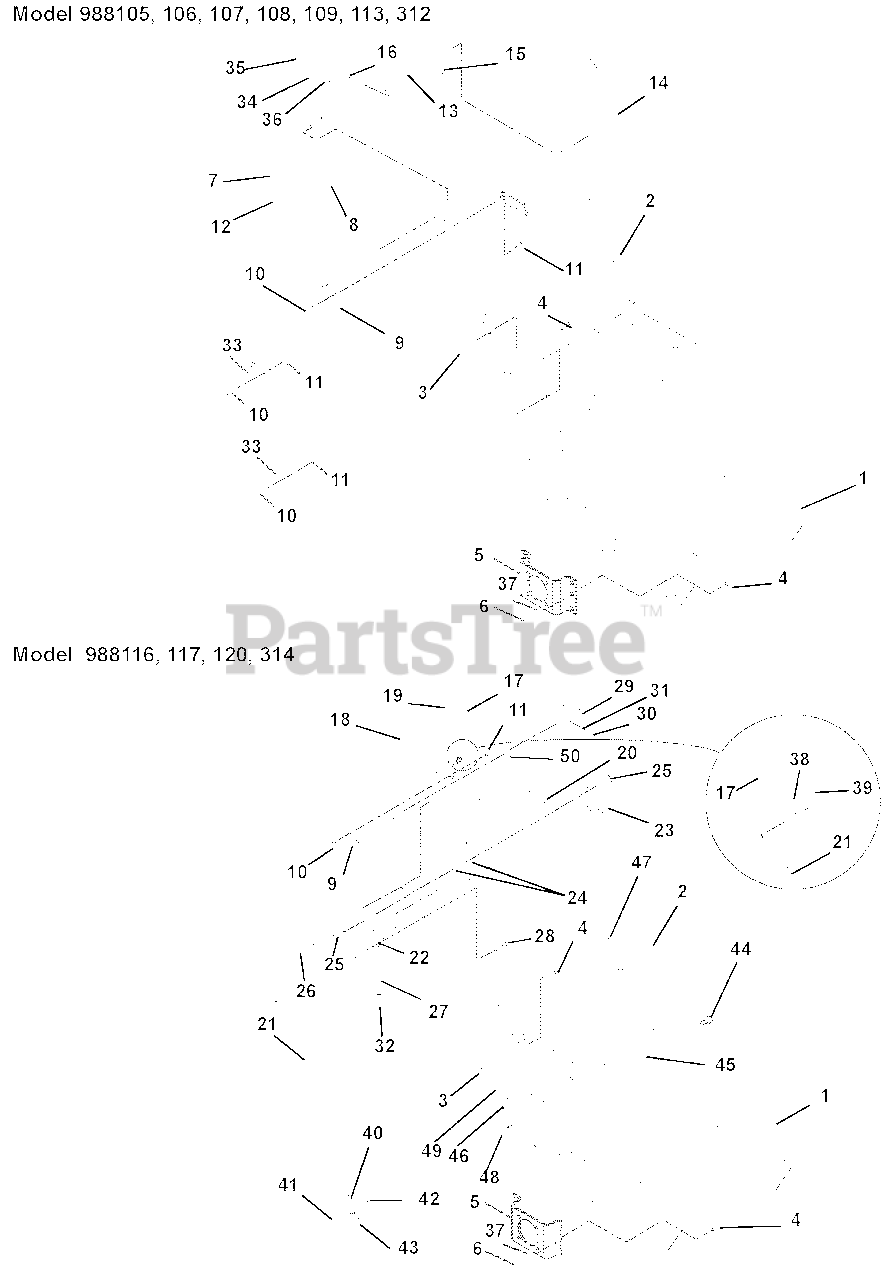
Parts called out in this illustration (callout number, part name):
1	Kit-Frame with Decals
2	Kit-Handlebar with Decals HR15 (105 - 107, 113, 312)
3	Bolt-Hex .38-16 x 1.00 Grade 5
4	Nut-Locking-Nylon .38-16
5	Bracket, Wheel Motor Left Hand (105, 107, 108, 116, 120, 312, 314)
6	Bolt-Hex .38-16 x 1.00 Grade 5
7	Grip, Handlebar (105, 106, 107, 108, 109, 113, 312)
8	Caplug, Handlebar (105, 106, 107, 108, 109, 113, 312)
9	Switch, Double Pole(105, 106, 107, 108, 109, 113, 312)
10	Screw, Machine 10-24 x .75 Hex Washer Head (105, 106, 107, 108, 109, 113, 312)
11	Nut-Locking-Nylon 10-24 with Insert (105 - 109, 113, 312)
12	Lever, Right Hand-Operator Presence (105, 106, 107, 108, 109, 113, 312)
13	Weldment, Pivot Tube (105, 106, 107, 108, 109, 113, 312)
14	Lever, Left Hand-Operator Presence (105, 106, 107, 108, 109, 113, 312)
15	Screw-Tapping 8-32 x .50 Hex Washer Head (105, 106, 107, 108, 109, 113, 312)
16	Spring-Tension .047 x .438 x 1.45 (105, 106, 107, 108, 109, 113, 312)
17	Weldment, Lever-Right Hand Speed Control(116, 117, 120, 314)
18	Lever- Operator Presence(116, 117, 120, 314)
19	Grip- Handlebar(116, 117, 120, 314)
20	Weldment- Speed Control Stop(116, 117, 120, 314) (Serial # 101-2999)
21	Rod, Steering (116, 117, 120, 314)
22	Weldment, Control Stop Limiter-Right Hand(116, 117, 120, 314) (Serial # 101-2999)
23	Weldment, Control Stop Limiter-Left Hand(116, 117, 120, 314)
24	Nut-Locking-Top-Flange .31-18(116, 117, 120, 314)
25	Bolt-Hex .31-18 x 1.75 Grade 5(116, 117, 120, 314)
26	Weldment, Speed Control Pivot- Right Hand(116, 117, 120, 314)
27	Lever- Control Stop Lock(116, 117, 120, 314) (Serial # 101-2999)
28	Bolt-Round Head Square Neck .31-18 x .75 Grade 5 (116, 117, 120, 314) (Serial # 101-2999)
29	Actuator, Switch(116, 117, 120, 314)
30	Pin-Roll .125 x .75(116, 117, 120, 314)
31	Nut-Push .312(116, 117, 120, 314)
32	Grip, Hand Clutch Lever (116, 117, 120, 314)
33	Switch- Double Pole N.O./N.O. (105, 106, 107, 108, 109, 113, 312)
34	Bracket, Brake Link (105, 106, 107, 108, 109, 113, 312)
35	Bolt, Hex .25-20 x .75 Grade 5 (105, 106, 107, 108, 109, 113, 312)
36	Nut, Locking Nylon .25-20 (105, 106, 107, 108, 109, 113, 312)
37	Washer, Flat Steel .406 x .812 x .065 (105, 106, 107, 108, 109, 113, 312)
38	Spring-Compression .045 x .60 x .75 (116, 117, 120, 314)
39	Pin-Hair Internal .08 x .18 x 1.18 (116, 117, 120, 314)
40	Yoke, .312-24 x 2.25 (116, 117, 120, 314)
41	Pin-Clevis .31 x .937 (116, 117, 120, 314)
42	Pin-Hair, Endries #25 (116, 117, 120, 314)
43	Washer-Flat-Steel .38 x .87 x .179 (116, 117, 120, 314)
44	Bolt-Hex .31-18 x 1.00 Grade 5 (116, 117, 120, 314)
45	Nut-Spin Lock-Flange .312-18 (116, 117, 120, 314)
46	Weldment- Reverse Adjustment Bracket (116, 117, 120, 314)
47	Bolt-Hex .38-16 x .75 Grade 5 (116, 117, 120, 314)
48	Nut-Locking-Top-Flange .38-16 (116, 117, 120, 314)
49	Bolt-Hex .31-18 x 1.25 Grade 5 (116, 117, 120, 314)
50	Washer, Wave (116, 117, 120, 314)
